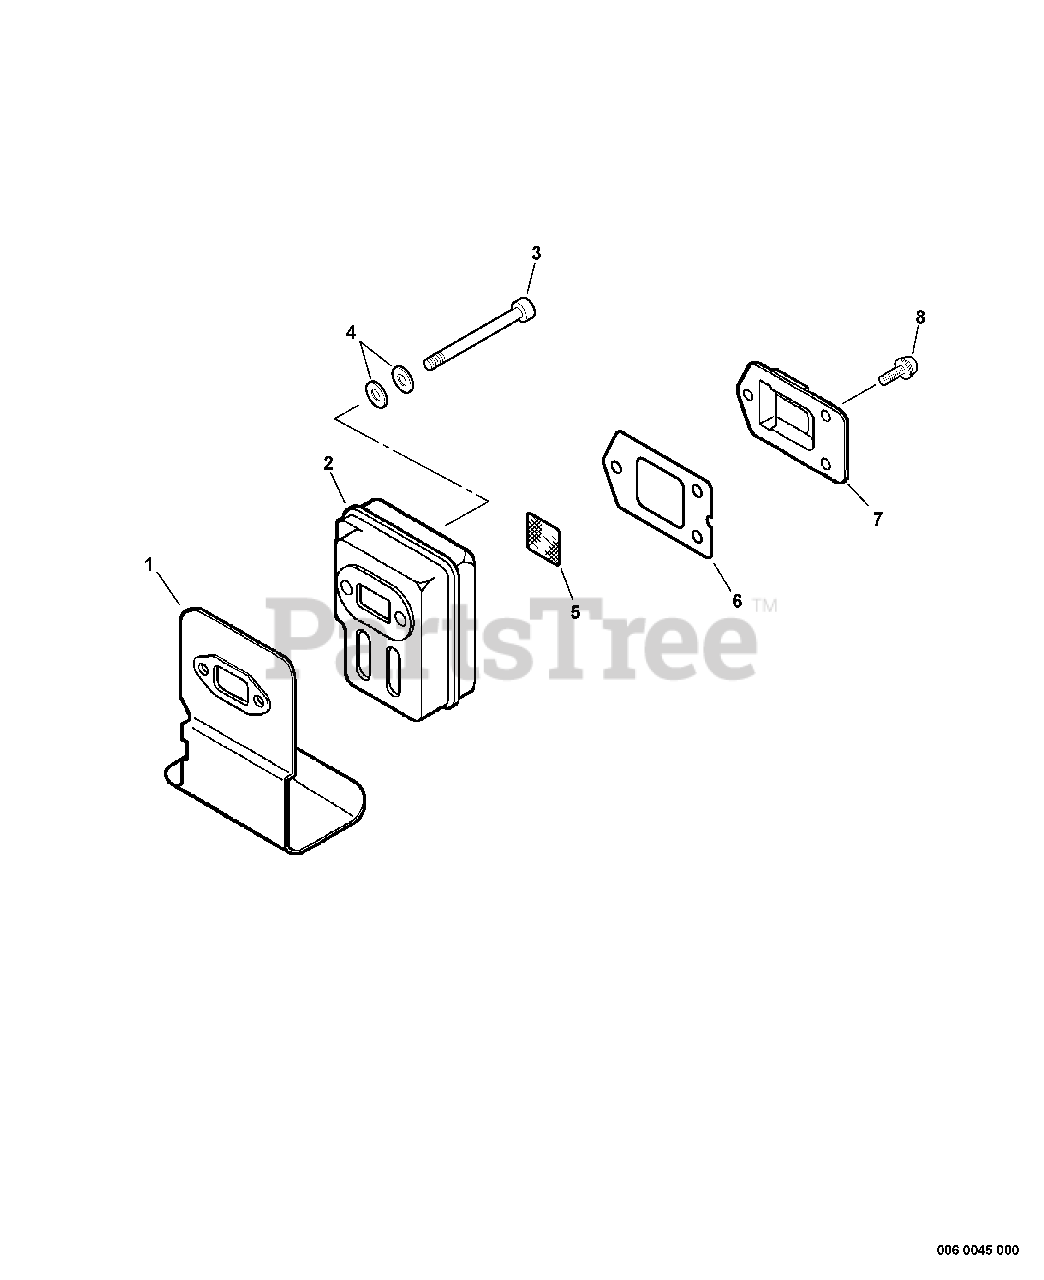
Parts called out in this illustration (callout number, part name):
1	SHIELD, EXHAUST
3	SCREW - 5X50
4	WASHER - 5
5	SCREEN, SPARK ARRESTOR
6	GASKET, EXHAUST
7	GUIDE, EXHAUST
8	SCREW - 4X10
